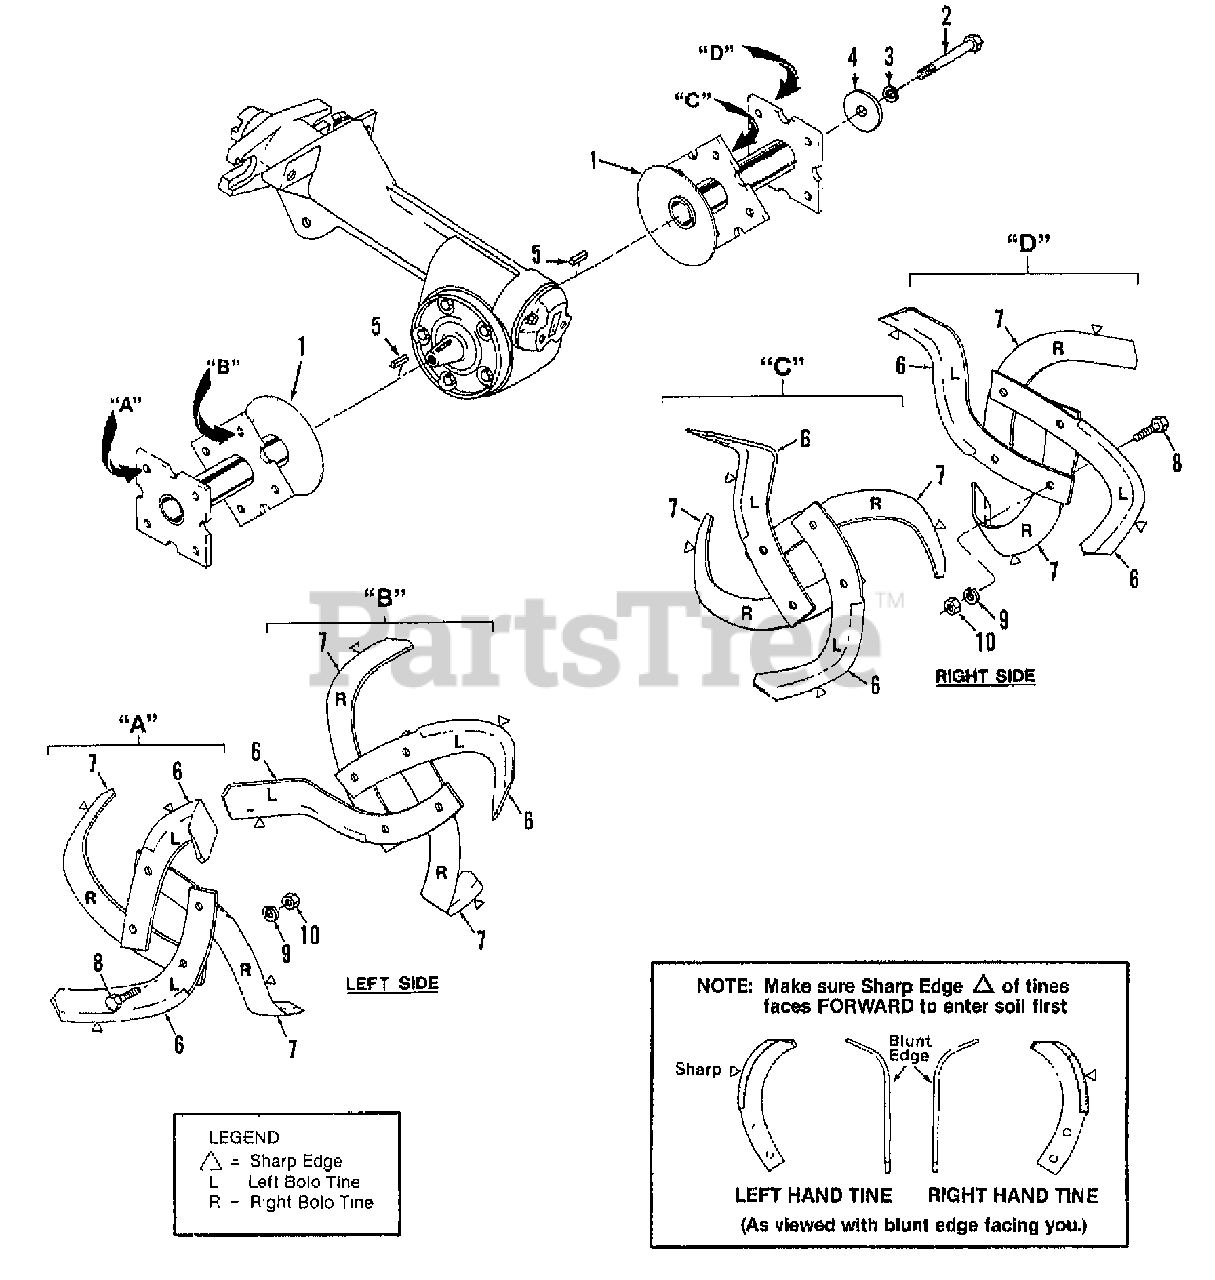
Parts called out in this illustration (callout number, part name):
1	HOLDER-TINE RED
2	SCR-HH 1/2-20X4.75 GR5
3	WASHER-LK .5
4	WASHER-1.5X.531X.187
5	KEY-.188 SQX1.0
6	TINE-BOLO LT W/HDW
7	TINE-BOLO RT W/HDW
8	SCR-HH 3/8-16X1.0 G5 ZP
9	WASHER-LK .375 @ DEPL
10	NUT-HEX 3/8-16 ZP
